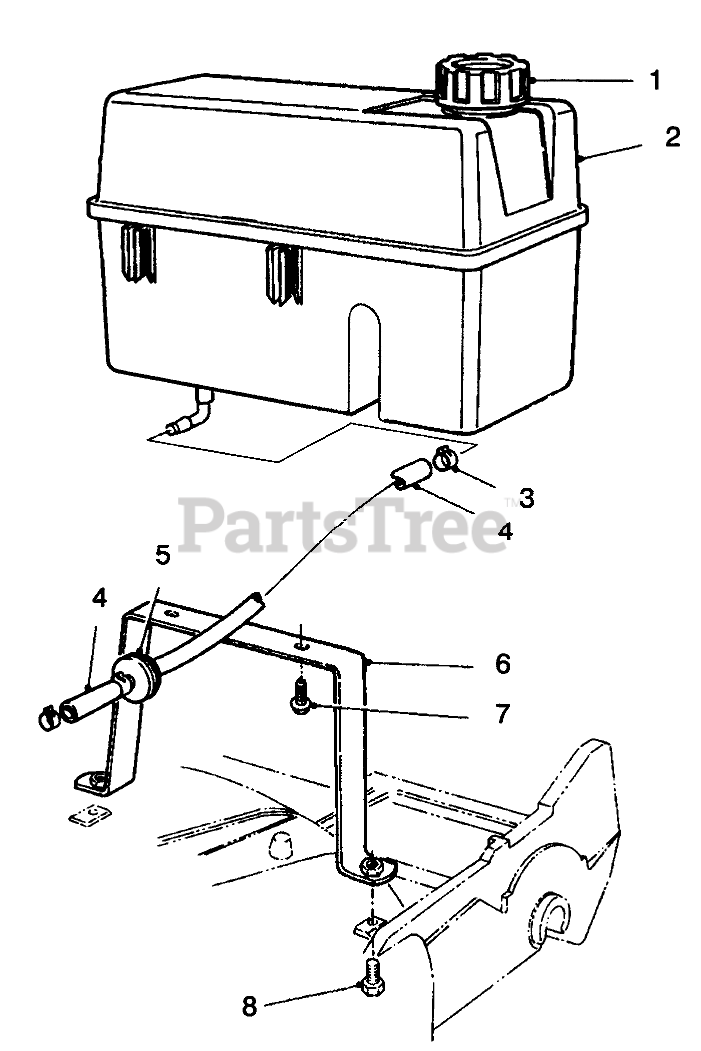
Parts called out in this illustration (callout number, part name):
1	GAS CAP ASM
2	TANK - FUEL
3	CLAMP-FUEL LINE
4	HOSE-FUEL
5	FILTER-FUEL
6	Wa-Base
7	SCREW-HWH
8	SCREW-HH
